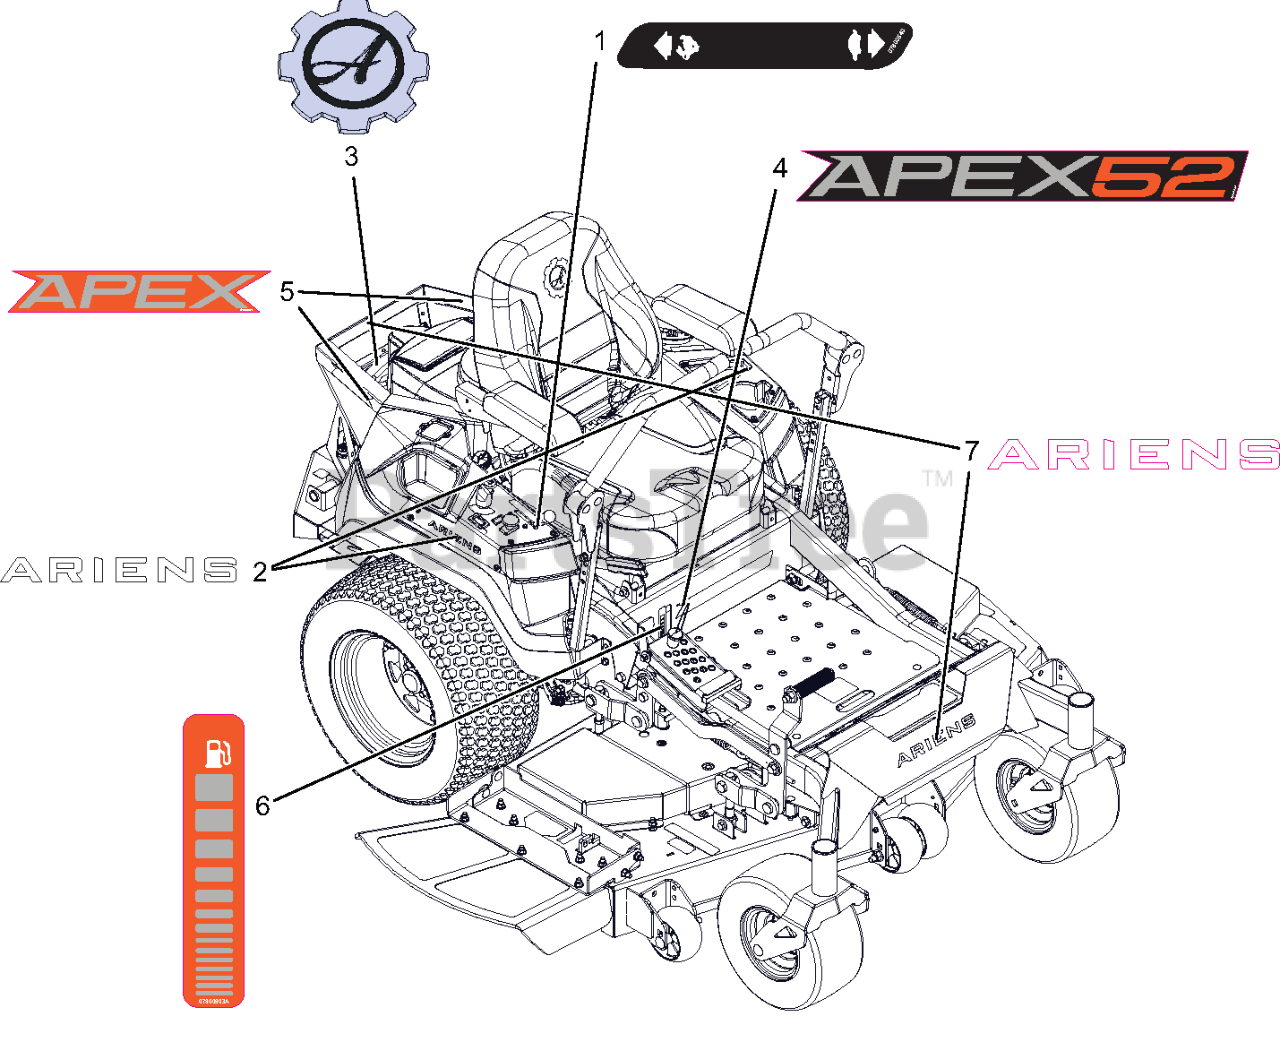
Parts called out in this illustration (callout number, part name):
1	DECAL, DASH DECAL
2	DECAL, ARIENS (6.50")
3	DECAL, ARIENS-GEAR BADGE -THK
4	DECAL, 52" APEX KICKPLATE
5	DECAL, APEX FENDER
6	DECAL, ARIENS FUEL LEVEL
7	DECAL - ARIENS 9.625"
